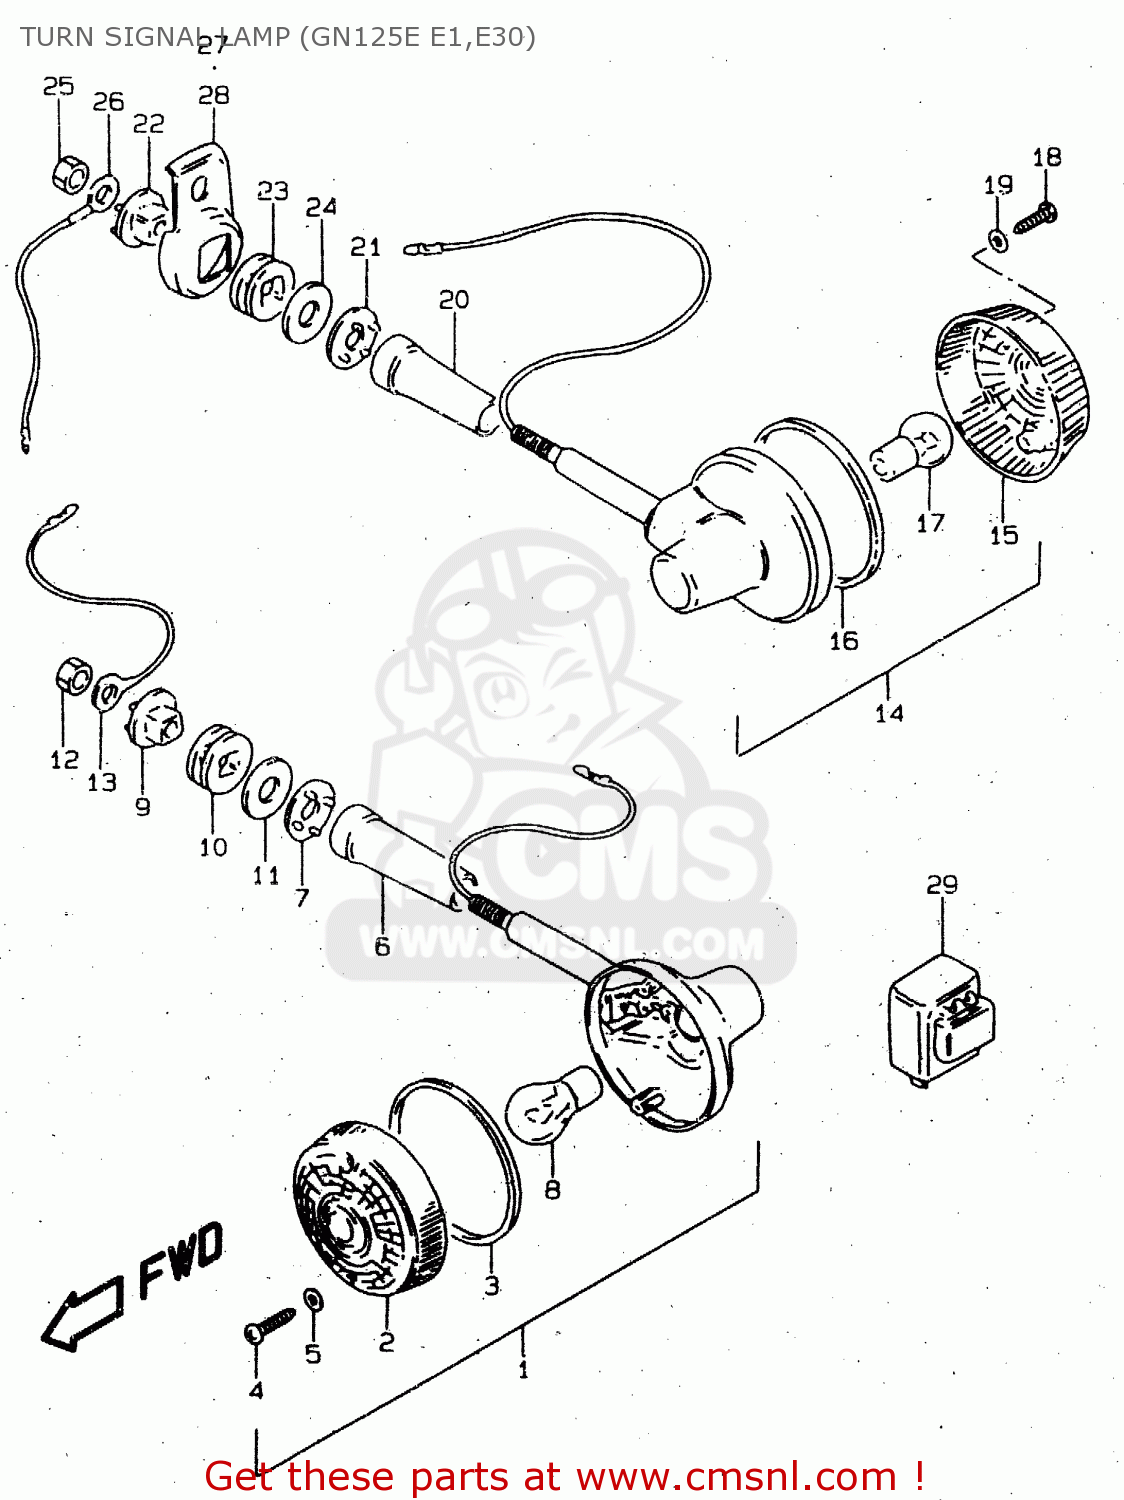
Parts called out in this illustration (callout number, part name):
1	LAMP ASSY,TURNSIGNAL
2	LENS
3	GASKET (NAS)
4	SCREW
5	GASKET (NAS)
6	COVER,STAY
7	CUSHION
8	BULB(12V23W,STANLEY,A4577A)
9	SPACER
10	CUSHION
11	WASHER(10.5X30X2.3)
12	NUT
13	LEAD WIRE,EARTH
14	LAMP ASSY,RR TURNSIGNAL
15	LENS
16	GASKET (NAS)
17	BULB(12V23W,STANLEY,A4577A)
18	SCREW
19	GASKET (NAS)
20	COVER
21	CUSHION
22	SPACER
23	CUSHION
24	WASHER(10.5X30X2.3)
25	NUT
26	LEAD WIRE,EARTH
27	BRACKET,RR TURNSIGNAL LAMP,R
28	BRACKET,RR TURNSIGNAL LAMP,L
29	RELAY ASSY,TURNSIGNAL
